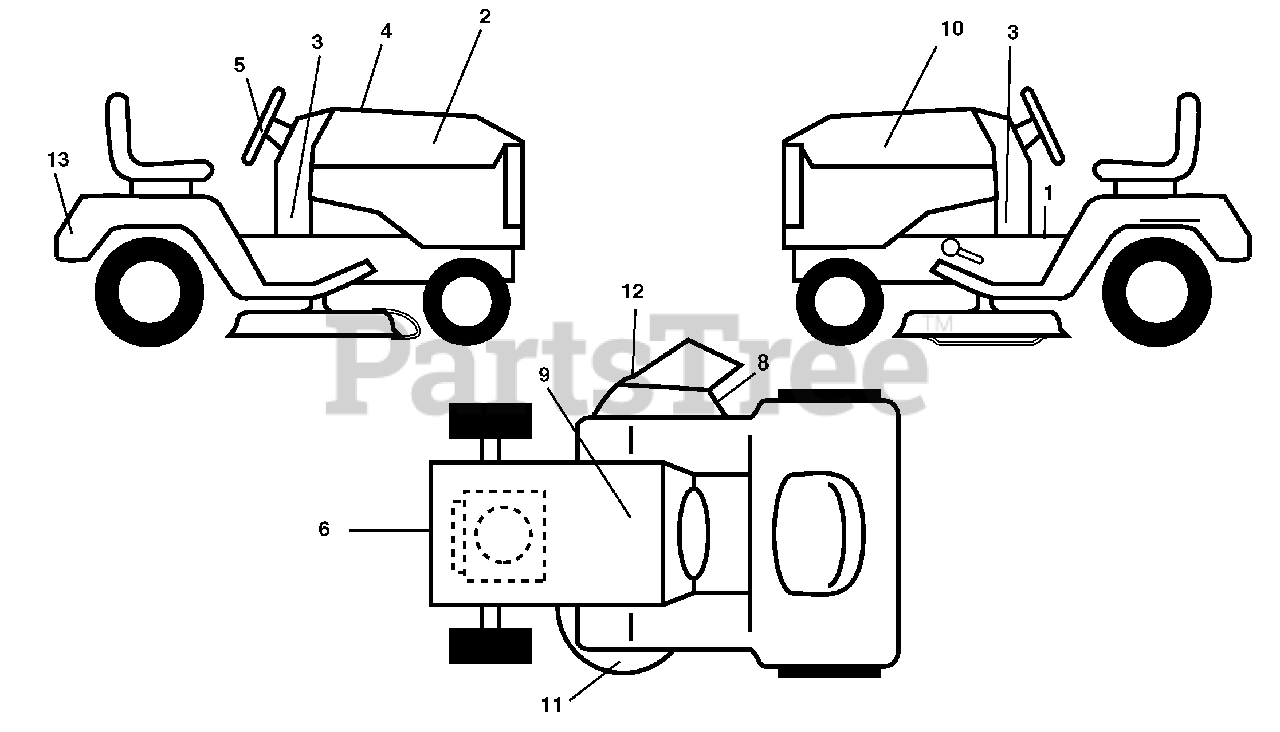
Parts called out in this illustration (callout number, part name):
1	Decal, Operator's
2	Decal, Hood RH
3	Decal, Dash Lower
4	Decal, Replacement
5	Decal, Strg Whl
6	Decal, Engine HP
8	Decal, Mower Sch.
9	Decal, Battery Dnge/Poi
10	Decal, Hood LH
11	Decal, Mower Caution
12	Decal, Mower Warning Keep Hand Away
13	Decal, Fender
13	Decal, Bypass
13	Pad, Footrest, LH
13	Pad, Footrest, RH
13	Manual, Operator's E&SP
13	Manual, Parts
